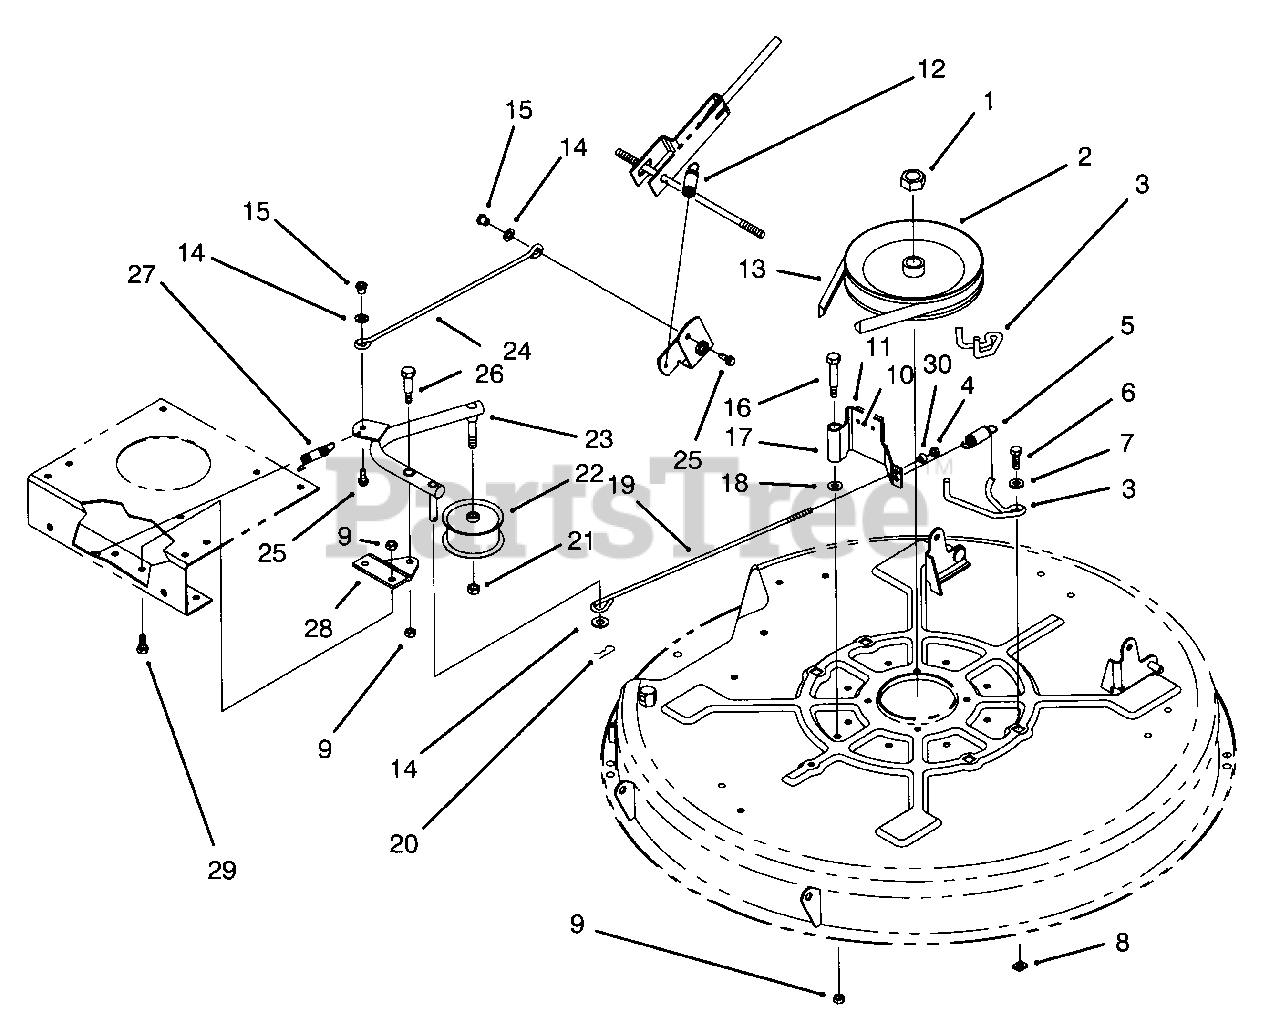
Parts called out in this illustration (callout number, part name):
1	Nut-Lock
2	Pulley-Deck
3	Guide-Belt
4	Nut-Lock
5	Spring-Extension
6	Screw-Hex Hd. Cap
7	Washer-Fender
8	Nut-Retained
9	Nut-Lock
10	Rivet-Pop
11	Pad-Brake
12	Spring/Cable Assembly
14	Washer-Flat
16	Bolt-Shoulder
17	Deck Brake Assembly (Incl. Ref. #10 & 11)
18	Washer-Flat
19	Rod-Deck Brake
20	Pin-Hair Cotter
21	Nut-Lock
22	Pulley-Idler
23	Arm-Idler
24	Rod-Deck Engage
25	Screw-Hex Flange Hd.
26	Bolt-Shoulder
27	Spring-Extension
28	Plate-Idler Mount
29	Screw-Hex Hd. Cap
30	Ball-Swivel
